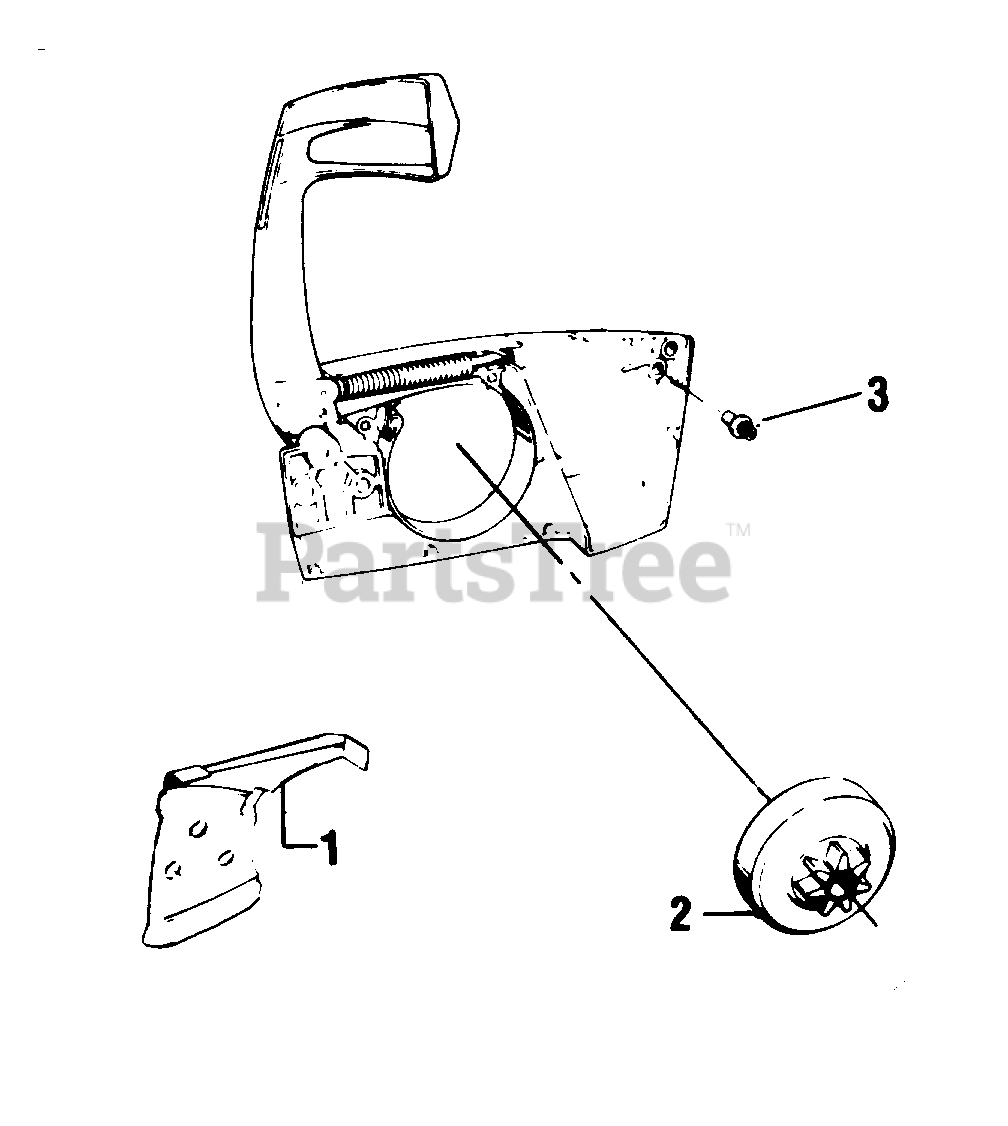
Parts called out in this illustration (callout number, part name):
1	Guide Bar Plate - Oiler
2	Drum & Sprocket Ass'y.
3	Bar Clamp Guide Stud Ass'y.
